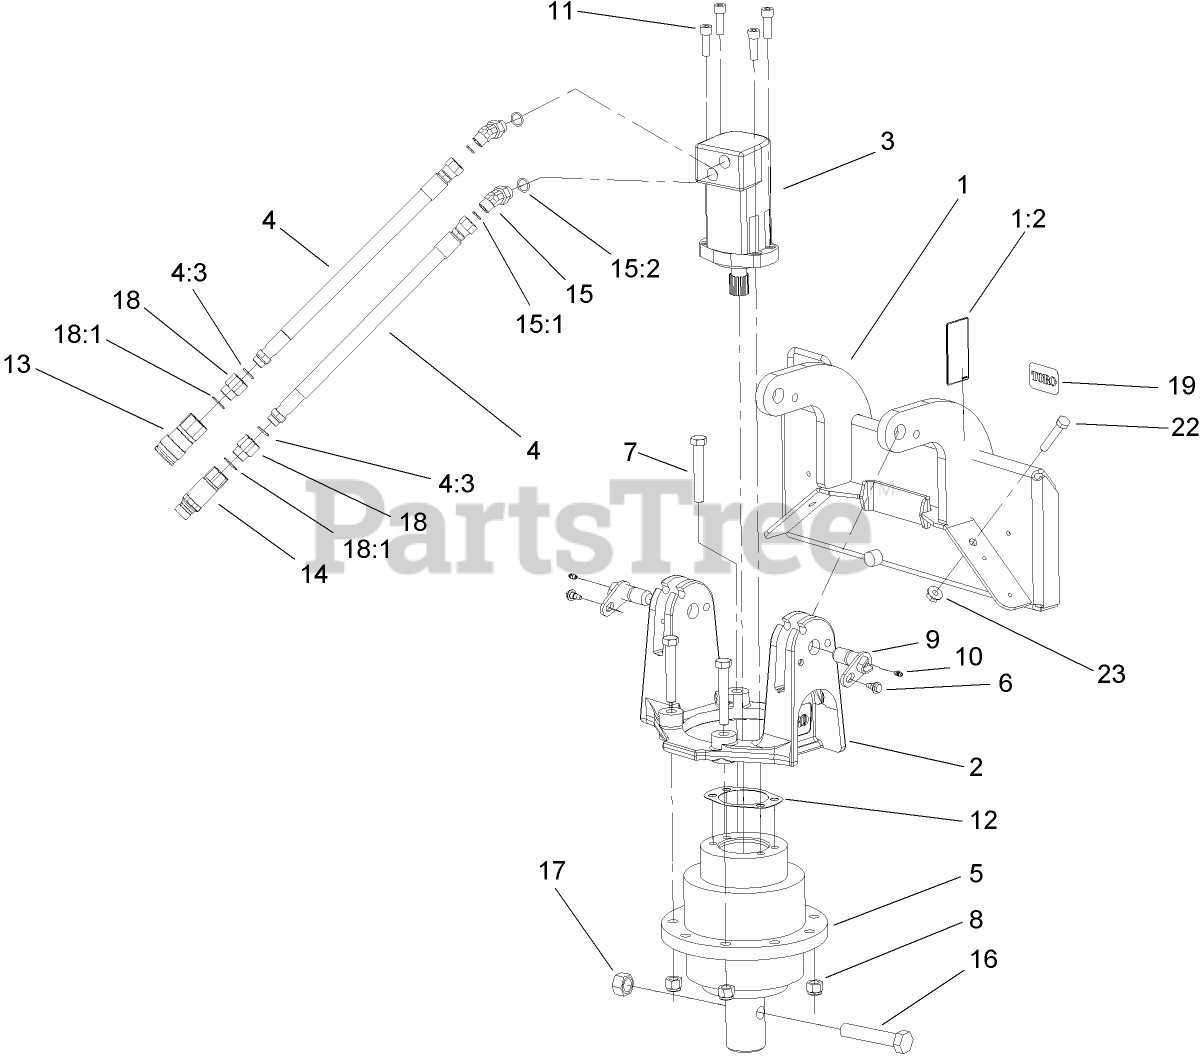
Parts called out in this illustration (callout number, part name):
1	AUGER MOUNT ASM
1:2	DECAL-DANGER
3	HYDRAULIC MOTOR ASM
4	HYD HOSE ASM
4:3	O-RING
5	DRIVE-PLANETARY
6	BOLT-SHOULDER
7	SCREW-HH
8	NUT-LOCK, NI
9	PIN-PIVOT
10	FITTING-GREASE
11	SCREW-HSH
12	GASKET
13	COUPLER-FACE, FLUSH
14	NIPPLE-CONNECT, PRESSURE
15	FITTING-HYD, 45 DEG
15:1	O-RING
15:2	O-RING
16	SCREW
17	NUT-HEX
18	ADAPTER-HYD
18:1	O-RING
19	DECAL
22	SCREW-HH
23	NUT-HHF
